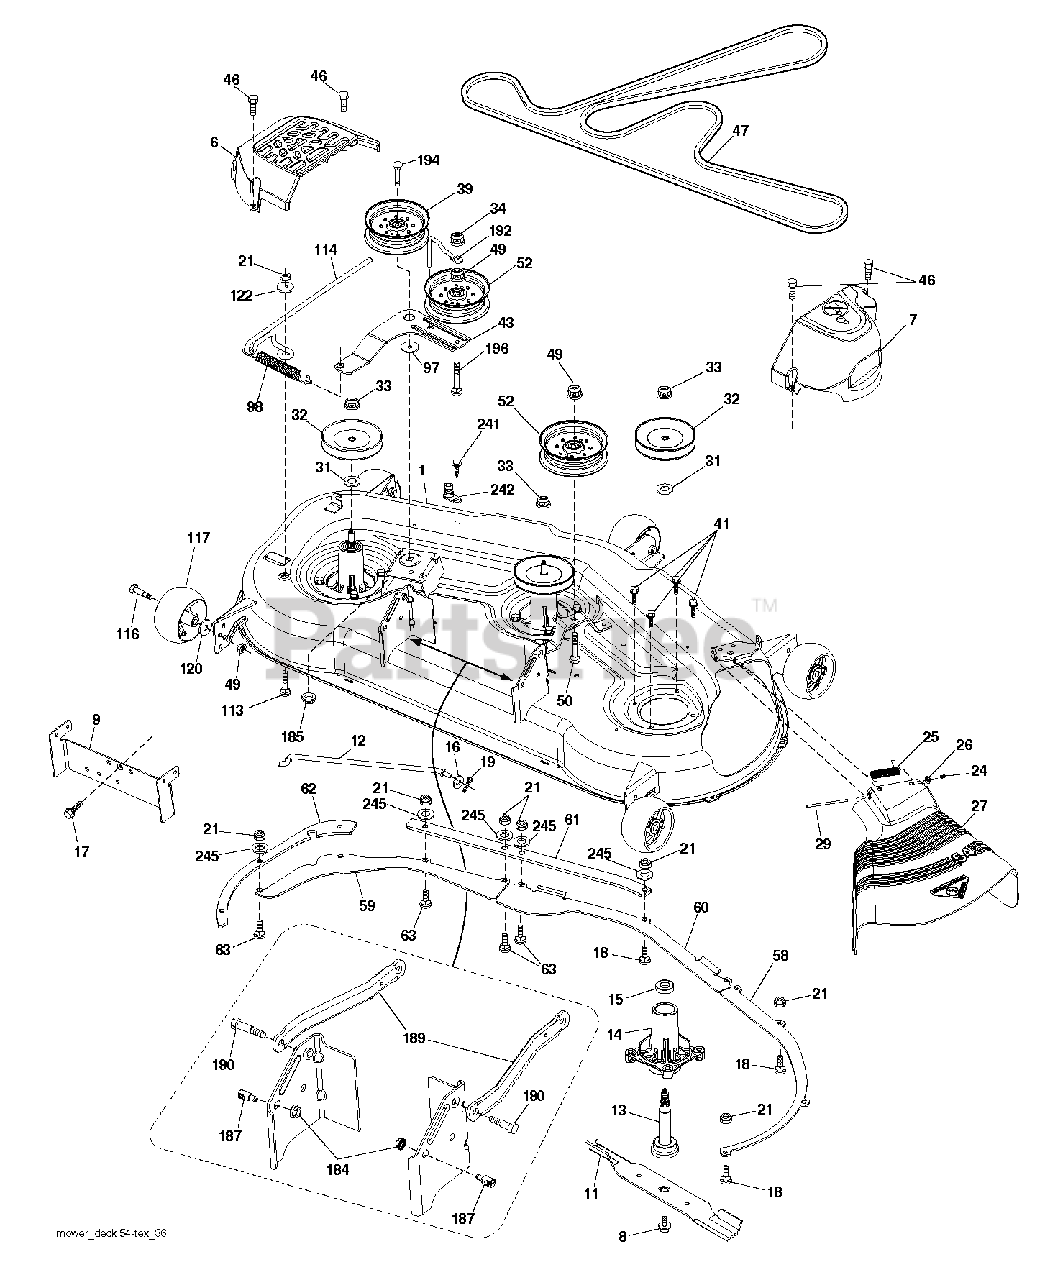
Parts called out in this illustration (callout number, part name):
1	DECK.SVC.54"
6	COVER.MANDREL.LH.54"20
7	COVER.MANDREL.RH.54.20
8	BOLT.WASHER.ASM.7/16-2
9	TORQUE STRAP PNT BLACK
11	BLADE.BAGGING.54"
12	ROD.ANTI.SWAY.48/54"K4
13	SHAFT ASM MANDREL
14	HOUSING.MANDREL.4PT.
16	WASHER
17	SCREW
18	BOLT
19	PIN.COTTER.5/16.BOW TI
21	LOCKNUT
24	CAP-SLEEVE LT
25	SPRING, TORSION
26	NUT PUSH M
29	ROD.HINGE
31	WASHER.SPACER.MANDREL
32	PULLEY/MANDREL
33	NUT.FLANGE.LOCK.TOP
34	LOCKNUT
39	PULLEY.IDLER.4.50/HUB SPECIAL
41	Hex Washer Head Bolt, .313-18 X 1.19
43	ARM.IDLER
46	SCREW.1/4-20X5/8
47	BELT.DRIVE.54."2006
49	NUT LOCK FLG 3/8-16 UNC
50	BOLT
52	PULLEY.IDLER.2006
58	BAFFLE.RIGHT.54"
59	BAFFLE.LEFT.54"
60	BAFFLE CENTER 54" MOWER
61	Front Bolt Reinforcement Plate, 54" X 431
62	Side Bolt Reinforcement Plate, 54" X 431
63	BOLT.CARRIAGE.5/16-18
98	SPRING, DECK DRIVE
113	BOLT CRT
114	ROD TENSION RELIEF
116	BOLT.SHOULDER.3/8-16X3-5/8.
117	WHEEL. GUAGE RALLY
122	BUSHING.RELIEF.TENSION
184	NUT LOCK HEX FLANGE 5/16-18
185	NUT.LOCK.FLANGE.7/16
187	STUD.FASTNER.W/ANTI-ROTATE
189	ARM.SUSPENSION.MOWER
190	BOLT.SHOULDER
192	KEEPER.BELT.IDLER.54"T
194	BOLT.HEX.WASHER.HEAD.7/16-24X
196	BOLT
241	SCREW.TT.#10-32X.5.3/8.FLANGE
242	PORT.WASHOUT
245	WASHER
